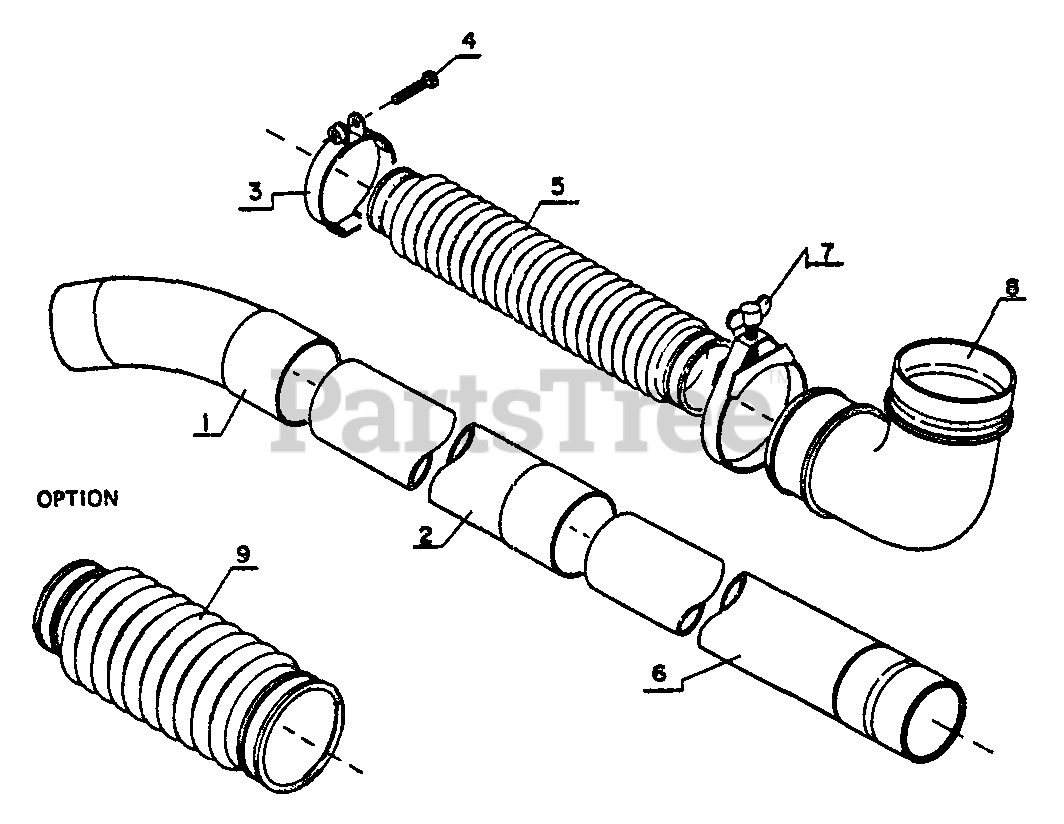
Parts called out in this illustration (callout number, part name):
1	TUBE, BLOWER - CURVED
2	TUBE, BLOWER - STRAIGHT
3	CLAMP
4	SCREW 5×20
5	TUBE, FLEXIBLE
6	TUBE, BLOWER - SWIVEL
8	TUBE, BLOWER - ELBOW
9	TUBE, BLOWER - FLEXIBLE
